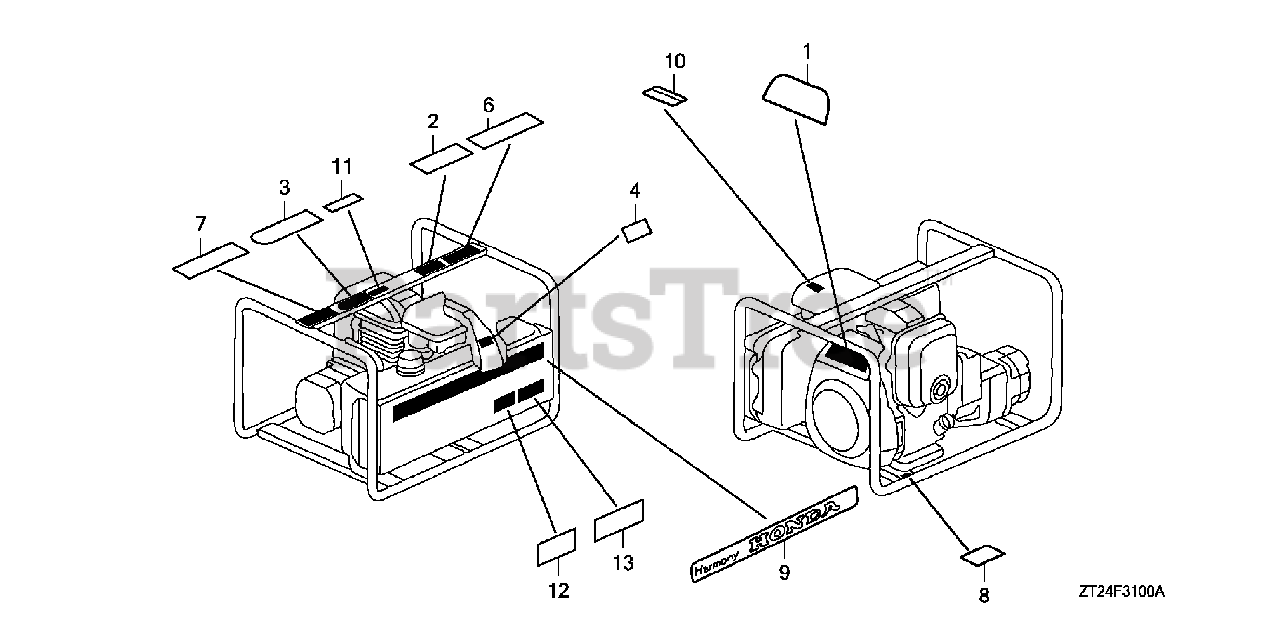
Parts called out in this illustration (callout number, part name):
1	PLATE, CAUTION (EN2000)
3	MARK, CAUTION (ENGLISH/FRENCH/SPANISH)
4	MARK, CHOKE
7	LABEL, CONNECT WARNING (ENGLISH)
8	MARK, OIL CAUTION
9	EMBLEM (HARMONY)
10	MARK, OIL ALERT (ENGLISH)
12	LABEL, RAIN WARNING (ENGLISH)
13	MARK, CAUTION (ENGLISH/FRENCH/SPANISH)
